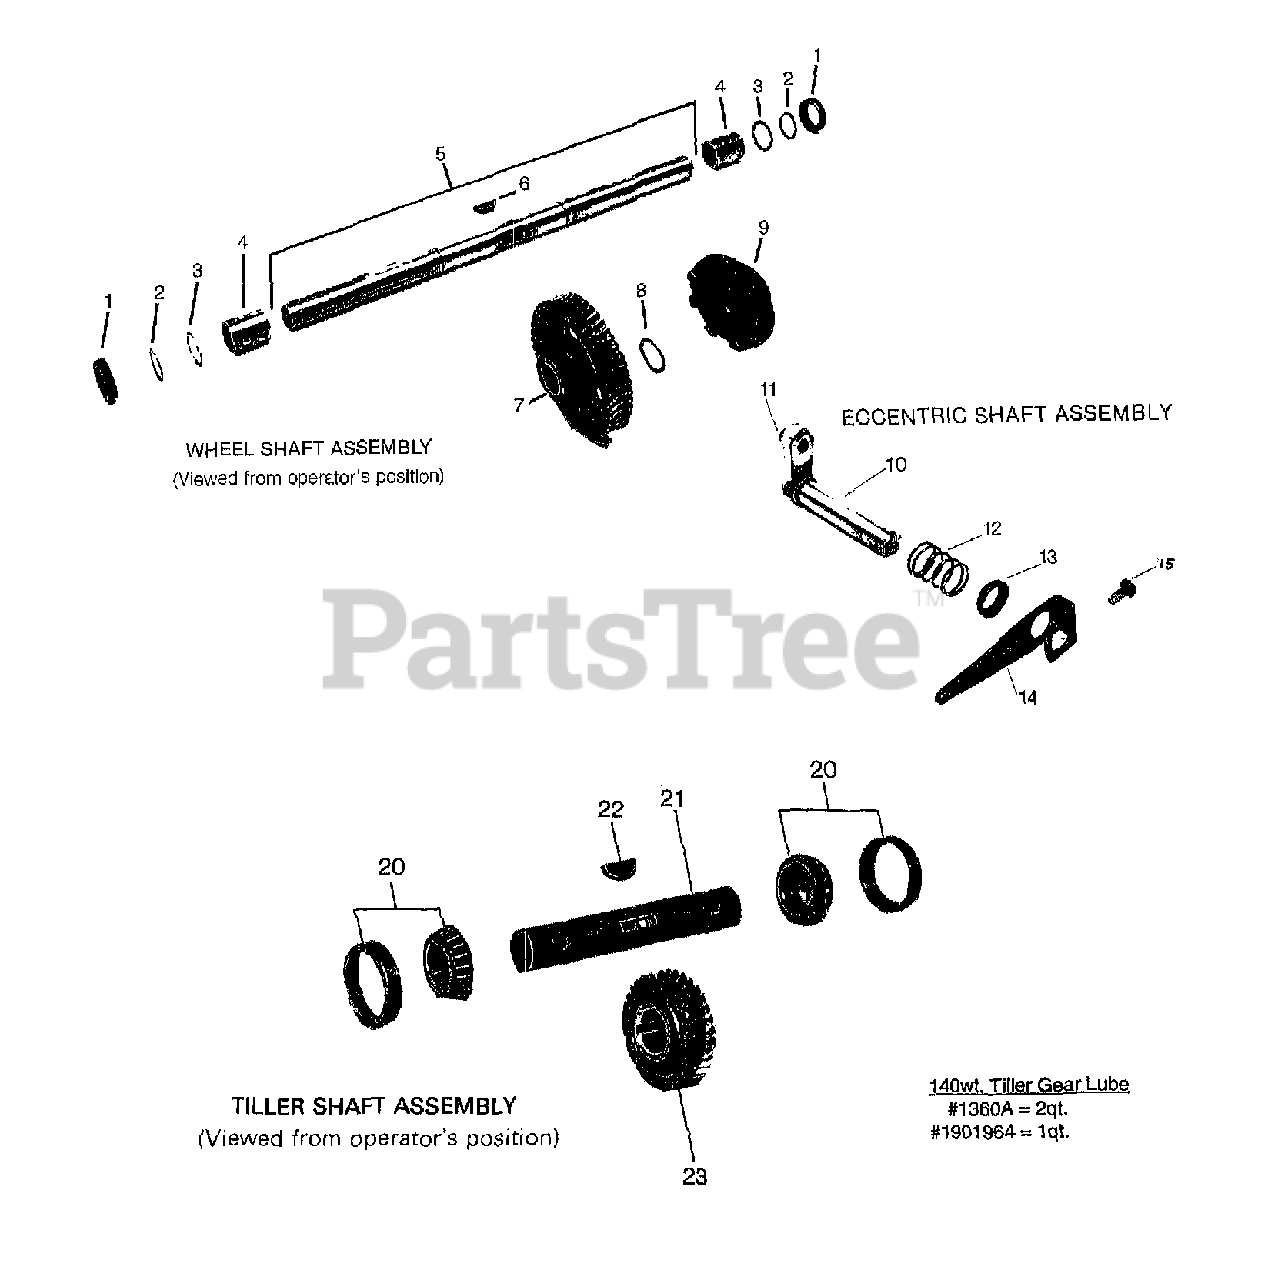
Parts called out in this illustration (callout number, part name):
1	OIL SEAL- left and right sides
2	RING -retaining, heavy-duty, external
3	SHIM-1 1/64" I.D., .062" thick
4	BUSHING-
5	WHEEL SHAFT-
6	KEY -Hi-Pro (1/4" x 1 5/16"), clutch to wheel shaft
7	GEAR-wheel drive (worm gear), cast iron
8	SHIM-between key and gear (1.016" I.D. x 1.468" O.D. x .062" thick)
9	CLUTCH- wheel drive, cast Iron
10	ECCENTRIC SHAFT-wheel clutch shifting
11	PIN- eccentric shaft
12	SPRING-
13	OIL SEAL- eccentric shaft
14	LEVER- eccentric shaft
15	BOLT-hex head, 1/4"-20 x 1/2"
20	BEARING - tapered roller (with race),
21	TILLER SHAFT-
22	KEY- woodruff, 1/4" x 1 1/4",
23	WORM GEAR - bronze, tiller drive
